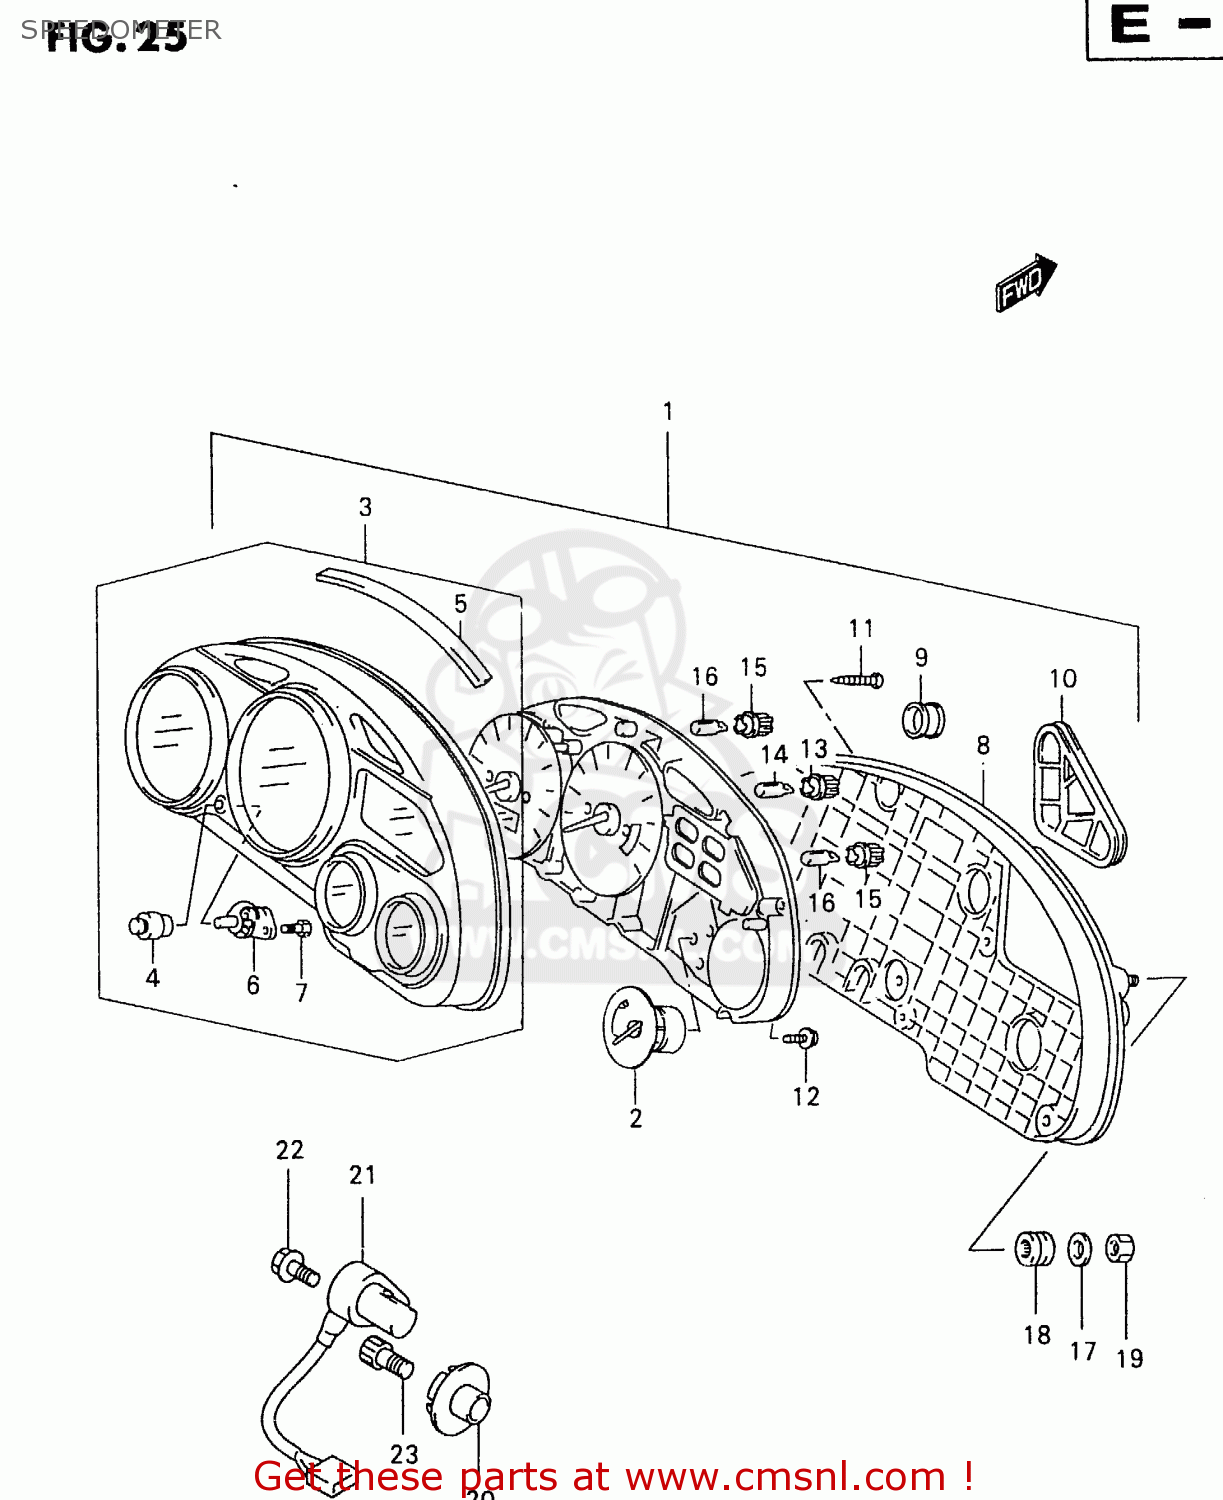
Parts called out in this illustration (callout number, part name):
1	SPEEDOMETER (KILO)
2	FUEL METER ASSEMBLY
3	VISOR ASSY
4	SWITCH,GUM
5	PACKING (NAS)
6	ATTACHMENT,SWITCH
7	SCREW(3X10)
8	CASE ASSEMBLY
9	CAP,BLIND NO.1
10	CAP,BLIND
11	SCREW
12	SCREW
13	SOCKET(T:6.5)
14	BULB(12V1.7W,T6.5)
15	SOCKET
16	BULB(14V1.4W,T5)
17	WASHER(6.5X22X1.6)
18	CUSHION
19	NUT 6MM
20	ROTOR,SPEED
21	SENSOR,SPEED
22	BOLT
23	BOLT
